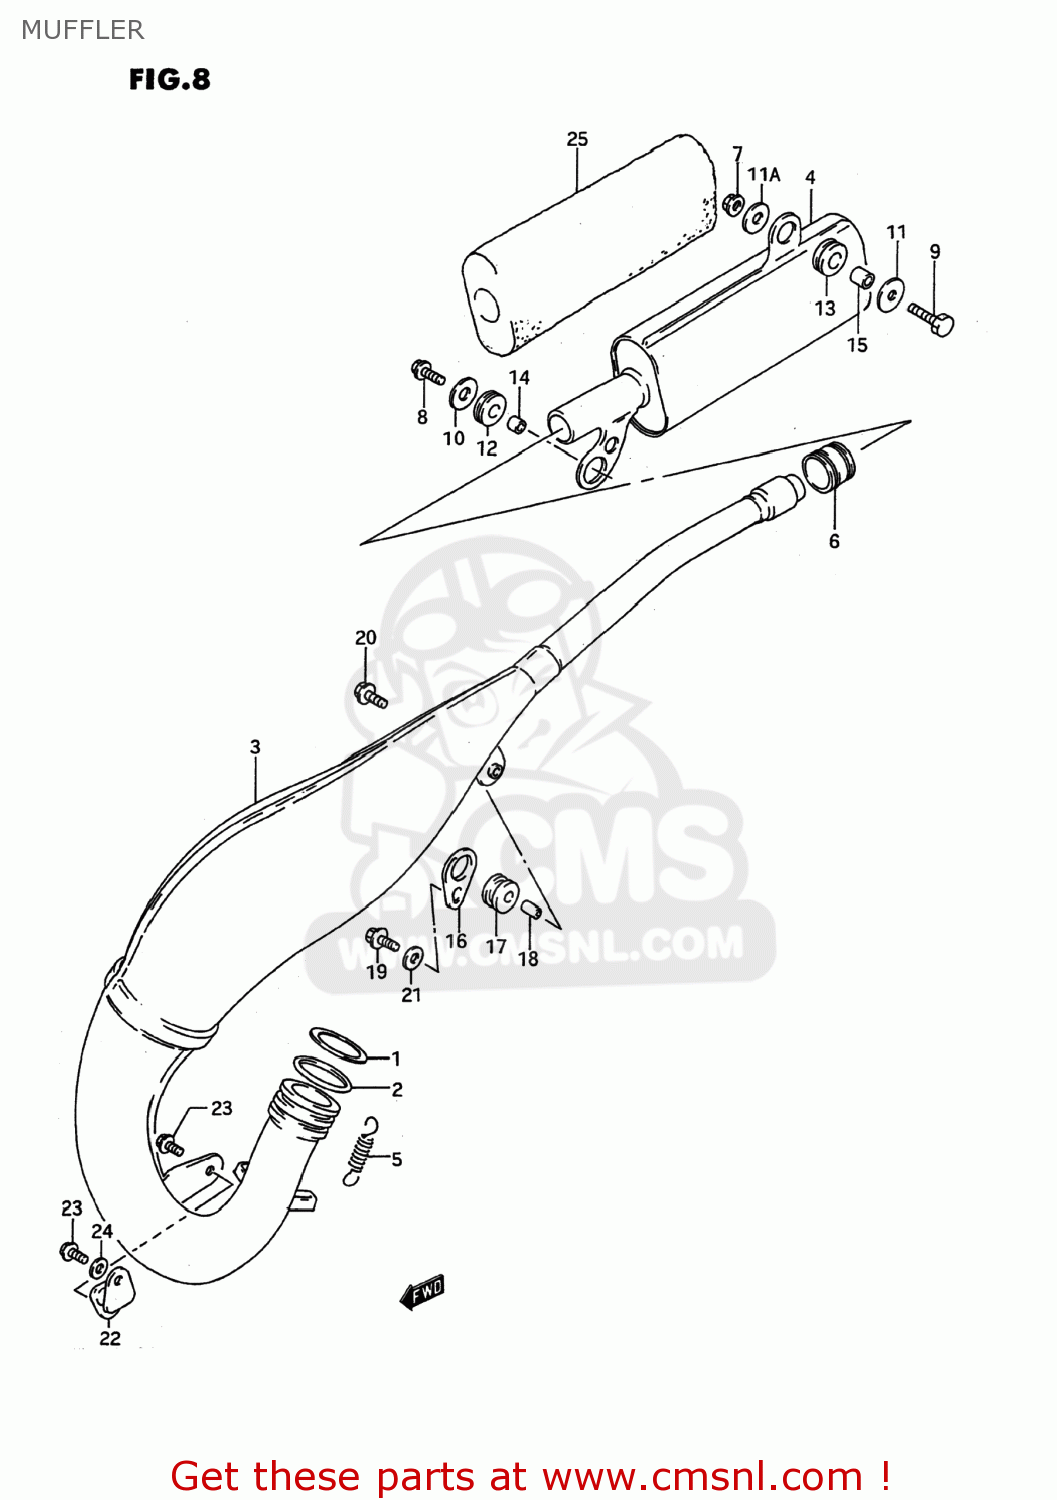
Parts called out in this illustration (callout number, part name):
1	WASHER,EXHAUST PIPE
2	O RING,EXHAUST PIPE
3	BODY,MUFFLER,FIRST
4	BODY,MUFFLER,SECOND
5	SPRING
6	CONNECTOR,MUFFLER
7	NUT
8	BOLT
9	BOLT
10	WASHER (6.5X24X1.2)
11	WASHER(8.5X26X1.2)
11A	WASHER (6.5X24X1.2)
12	CUSHION
13	CUSHION
14	SPACER (6.8X10X9)
15	SPACER(6.5X11.5X13)
16	PLATE,MUFFLER MTG
17	CUSHION,MUFFLER
18	SPACER (6.4X9X13.5)
19	BOLT
20	BOLT
21	WASHER
22	DAMPER,MUFFLER SUPPORT
23	BOLT
24	WASHER
25	SILENCER,MUFFLER
